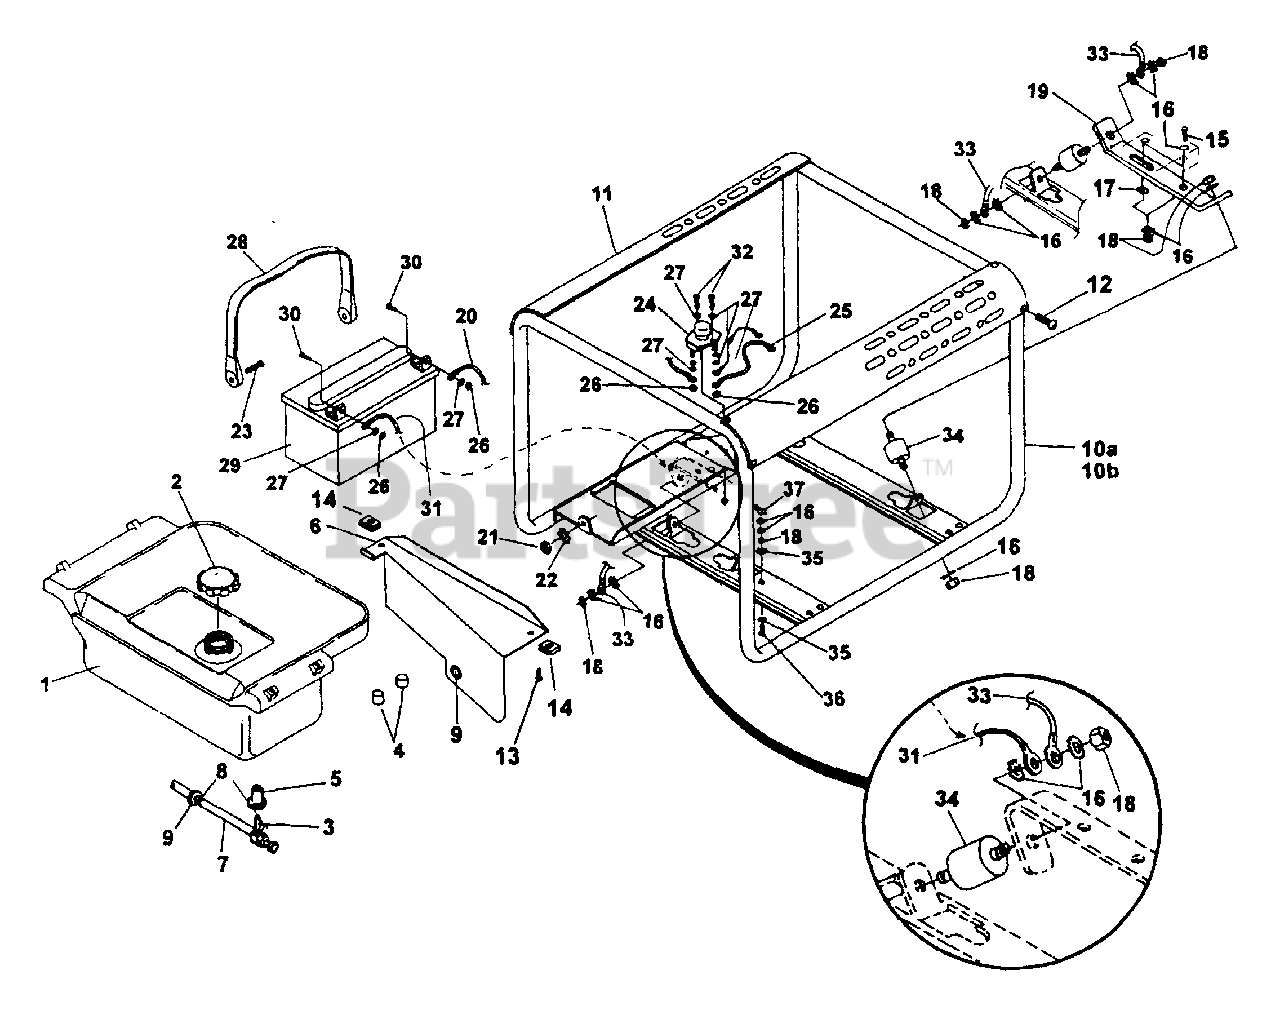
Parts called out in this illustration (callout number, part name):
1	FUEL TANK (5 Gal.)
2	FUEL CAP (2 1/4" dia.)
3	VALVE-Fuel
4	PAD-Fuel Tank
5	BUSHING
6	SHIELD-Fuel Tank
7	FUEL LINE
8	CLIP-Hose
9	BUSHING-Snap In
10A	ROLL CAGE (LR4400, LR5500, LR4400/CSA, LR5500/CSA)
10B	ROLL CAGE (LRE4400, LRE5500, LRE4400/CSA, LRE5500/CSA)
11	BRACE-Tank Support
12	SCREW-Torx (10-24 X 1/2")
13	SCREW-Pan Hd. (8-32 X 3/8")
14	NUT-Hi Speed
15	SCREW-Hex Hd. (5/16-18 X 2")
16	WASHER-Lock (int.)
17	WASHER-Flat
18	NUT-Hex (5/16-18)
19	SUPPORT-Engine
20	CABLE-Battery (Red, Pos.)
21	NUT-Hex (10-32)
22	WASHER-Lock
23	SCREW-Shoulder (10-32 X 1/4")
24	SWITCH-Starter
25	BATTERY CABLE (Red, to Switch)
26	NUT-Hex (10-32)
27	WASHER-Lock
28	STRAP-Battery Hold Down
29	BATTERY (12 Volt)
30	SCREW-Hex Hd. (1/4-20 X 5/8")
31	BATTERY CABLE (Black, to Ground)
32	SCREW-Hex Hd. (1/4-20 X 1/2")
33	GROUND STRAP
34	ISOLATOR
35	WASHER-Lock (ext./int.)
36	SCREW-Hex Hd. (5/16-18 X 1 1/2")
37	NUT-Wing
